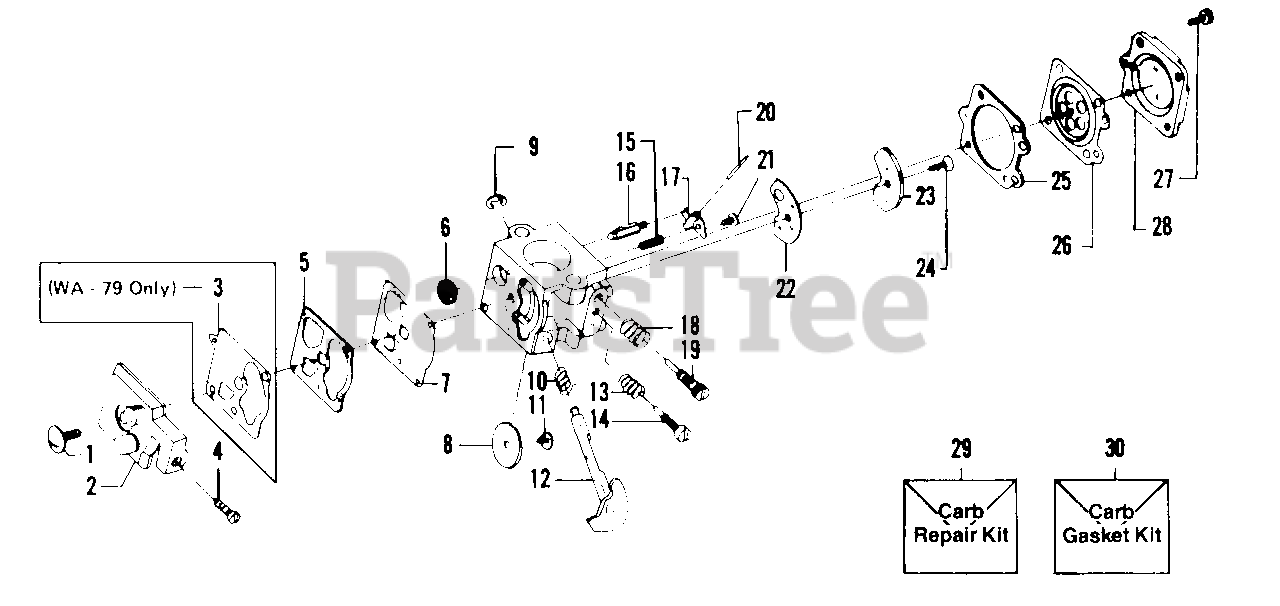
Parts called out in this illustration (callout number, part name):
1	Screw - Pump Cover
2	WA - 149 (# 35183)
3	Diaphragm - Pump (WA - 79 Only)
4	Screw - Idle Adjustment
5	Gasket - Pump
5	WA - 149 (# 35183)
6	Screen - Inlet
7	Diaphragm - Pump
7	WA-149 (# 35183)
8	Valve - Throttle
9	Clip - Throttle Shaft
10	Spring - Throttle Return
11	Screw - Throttle Valve
12	Shaft Assembly - Throttle
13	Spring - Idle Needle
14	Needle - Idle
15	Spring - Metering Lever
16	Valve - Inlet Needle
17	Lever - Metering
18	Spring - Hi Speed Needle
19	Needle - Hi Speed
20	Pin - Metering Lever
21	Screw - Metering Lever Pin
22	Gasket - Circuit Plate
23	Plate - Circuit
24	Screw - Circuit Plate
25	Gasket - Metering Diaphragm
26	Diaphragm Assembly - Metering
27	Screw - Assembly - Metering Cover & Throttle Shaft Clip
28	Cover - Metering Diaphragm
29	Kit - Carb Kwik Repair
29	WA - 149 (#35183)
30	Kit - Carb Gasket/Diaphragm Kit
30	WA - 79
30	WA - 149 (#35183)
